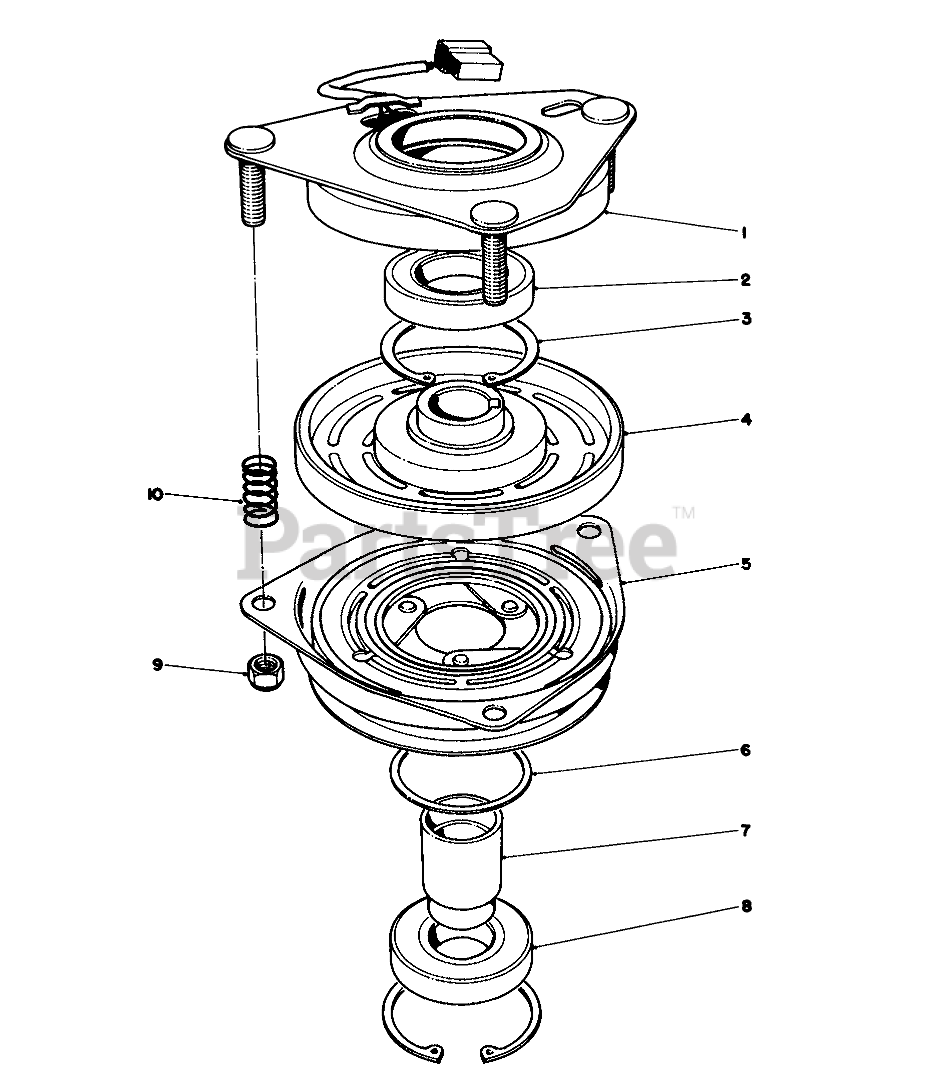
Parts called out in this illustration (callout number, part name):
1	Field Assembly (Incl. Ref. #2 & 3)
2	BEARING-FIELD
3	RING-RETAINING
4	Field Coil, Rotor And Bearing (Incl. Ref. #1)
5	Armature & Pulley Assembly (Incl. ref. #3, 6-8)
6	SPACER-BEARING, PULLEY
7	COLLAR-BEARING
8	BEARING-PULLEY
9	NUT-LOCK
10	SPRING
